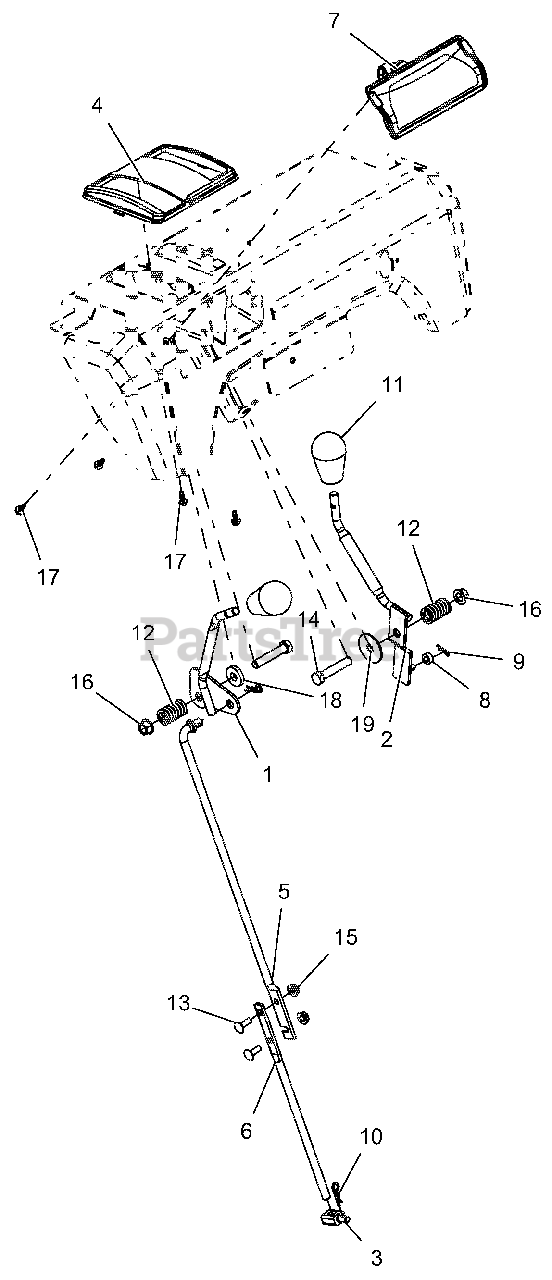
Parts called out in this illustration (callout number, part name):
1	WELDMENT, CONTROL LEVER(SHIFT)
2	WELDMENT, CONTROL LEVER (DEFL)
3	PIVOT,SHIFT ROD .375-16(TRUNN)
4	BEZEL, SHIFT
5	ROD, SHIFT - UPPER
6	ROD, SHIFT - LOWER
7	HEADLIGHT ASY, HALO 20W 2SHOT
8	BSHG-SLV .265X.500X.219
9	PIN-HAIR INT .06X.18X.77
10	PIN-HAIR INT .08X.18X1.18 YWZC
11	KNOB,SOFT TEARDROP,PUSH-ON GRY
12	SG-COMP .125X.781X1.250
13	@BLT-RDHDSQNK .25-20X.75 G5YZ
14	@BLT-HEX .38-16X2.00 GR5 YWZC
15	@NUT-LK-CTR-FLG .25-20 YWZC
16	@NUT-LK-TOP-FLG .38-16 YWZC
17	SCR-TAP #10X.50 BOSS INDHXHD
18	WSHR-FL-STL .406X1.00X.188 YWZ
19	WSHR-FL-STL .380X1.50X.062 YWZ
